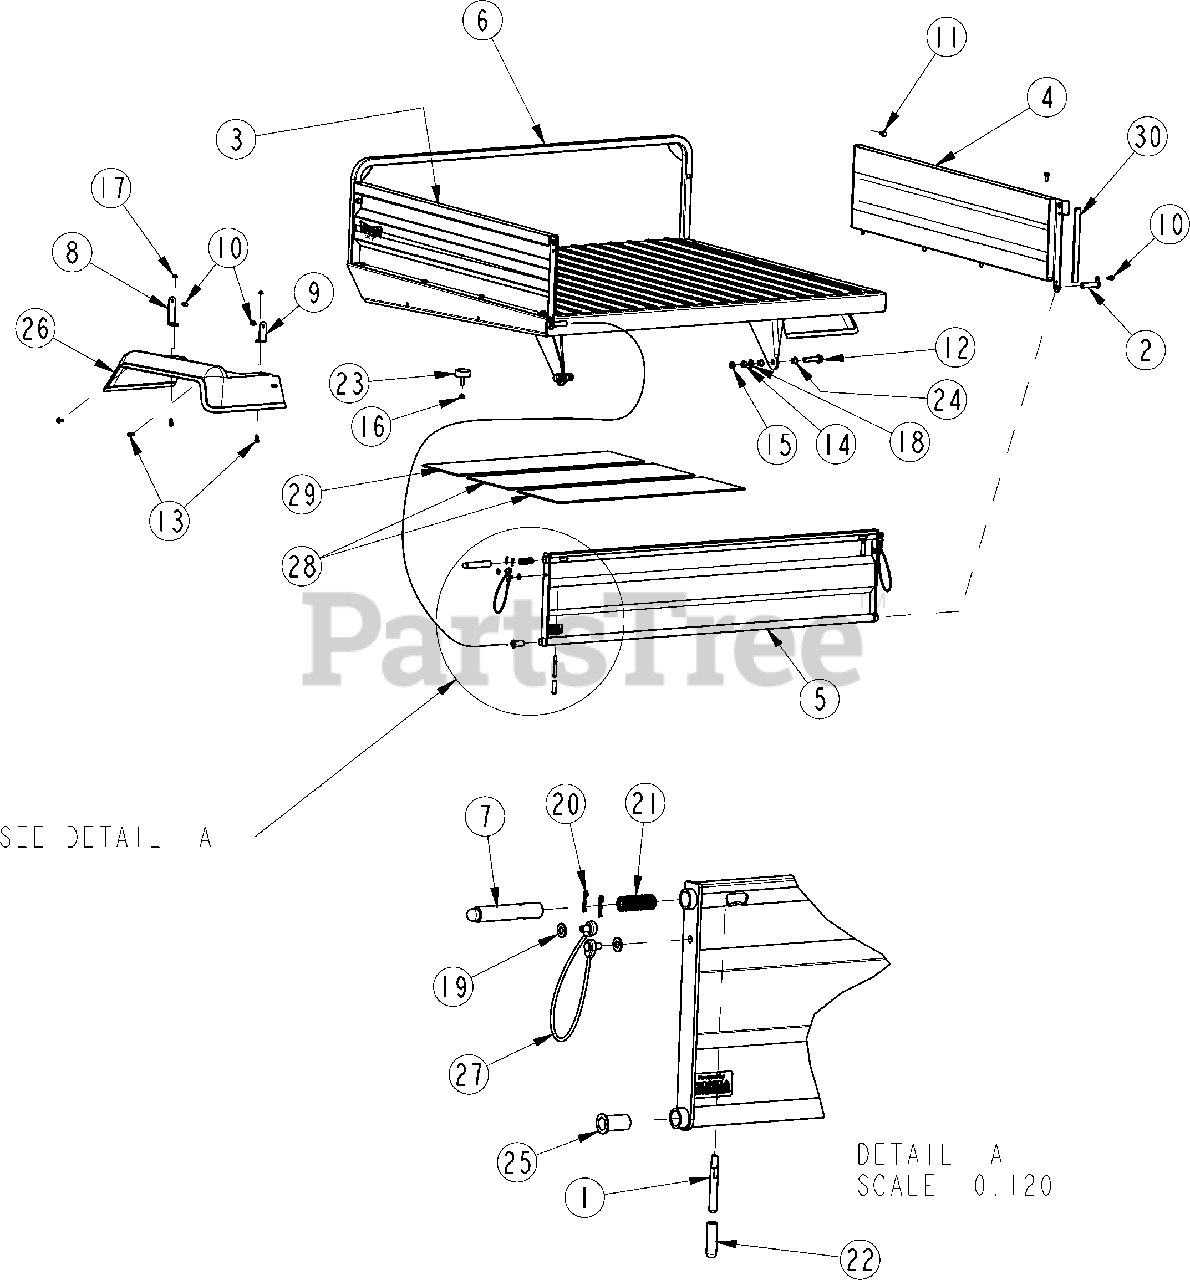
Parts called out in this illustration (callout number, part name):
1	TAILGATE LATCH HANDLE
2	WELDMENT, TAILGATE PIVOT
3	LH BED SIDE ASSY, RED 4220 Includes Decals
3	LH BED SIDE ASSY, RED 4420 Includes Decals
3	LH BED SIDE ASSY, CAMO Includes Camo Panel & Decals
4	RH BED SIDE ASSY, RED 4220 Includes Decals
4	RH BED SIDE ASSY, RED 4420 Includes Decals
4	RH BED SIDE ASSY, CAMO Includes Camo Panel & Decals
5	TAILGATE ASSEMBLY, RED Includes Decals, Latch & Bushings
5	TAILGATE ASSEMBLY, CAMO 4420 Includes Camo Panels, Decals, Latch & Bushings
6	BED BASE SUB-ASSY, BLACK Includes Decals, Inserts & Heat Shielding
7	LATCH PIN
8	BRACKET, FENDER MOUNT FRONT
9	BRACKET, FENDER MOUNT REAR
10	SCREW HEX SELF-TAP 1/4-20X 1/2
11	HFS 5/16-18X3/4 GR5
12	HFS 1/2-13X2 1/4 GR5 PLT
13	HFS 1/4-20X5/8 GR5 YLW
14	NUT LOCK 1/2-13 PLT
15	NUT HEX JAM 1/2-13 PLT
16	NUT HEX FLANGE 3/8-16 PLT
17	NUT HEX FLNG T-LOCK 1/4-20 YLW
18	WASHER FLAT 1/2 SAE PLT
19	WASHER FLAT 5/16 SAE PLT
20	PIN HAIR COTTER .059W 15/16LG
21	SPRING COMP .734ODX2.06X.072W
22	RUBBER TAILGATE LATCH SLEEVE
23	RUB. STOP 2" W/ 3/8X1.25 STUD
24	BUSHING 1/2IDX5/8ODX1/2 FLANGE
25	BEARING .75DX.625IDX1.5L W/FLG
26	FENDER BLACK UNIVERSAL TRUCK
27	TRUCK TAILGATE CABLE
28	HEAT SHIELD / INSUL BED
29	HEAT SHIELD / INSUL BED FRONT
30	SPONGE RUBBER, 1/4X3/4 W/PSA X 10" LG. Sold By The Foot
